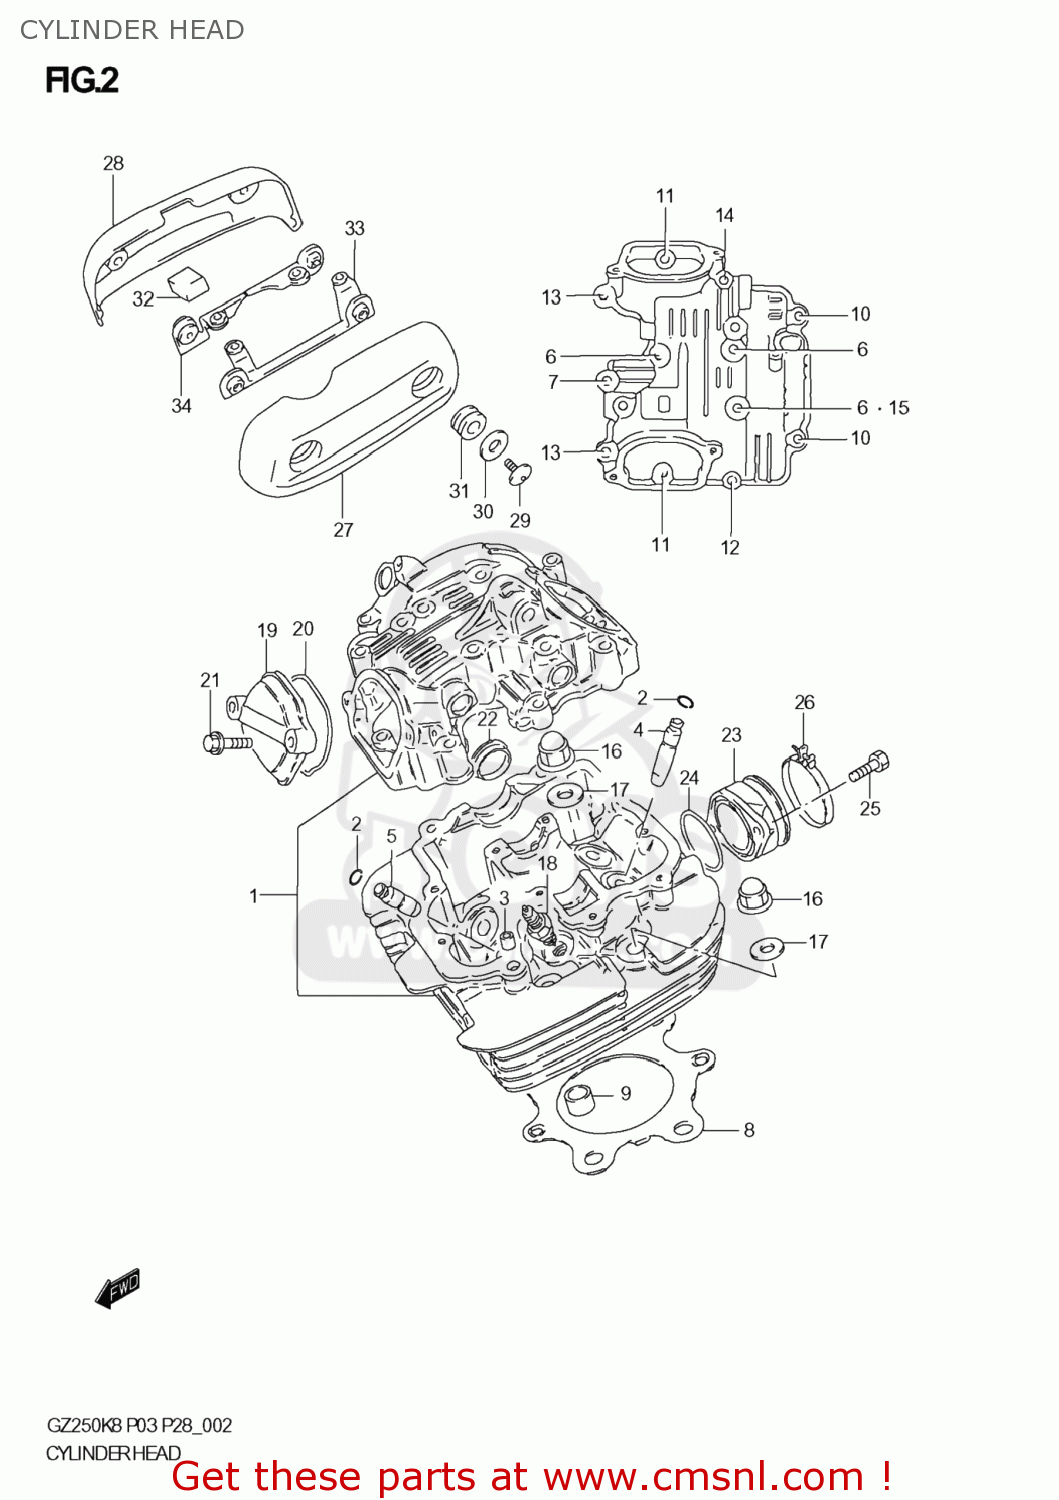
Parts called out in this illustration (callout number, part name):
1	HEAD ASSY,CYLINDER
2	RING,SNAP
3	PIN(6.2X8X11)
4	GUIDE,INTAKE VALVE
5	GUIDE,VALVE
6	BOLT
7	BOLT
8	GASKET,CYLINDER HEAD (NAS)
9	PIN
10	BOLT(6X120)
11	BOLT
12	BOLT
13	BOLT
14	BOLT
15	GASKET(5.8X13X1.2) (NAS)
16	NUT
17	GASKET(10.5X22X2) (NAS)
18	PLUG,SPARK(DR8EA)
19	CAP,INSPECTION
20	O RING(D:2.4,ID:23)
21	BOLT
22	PLUG(OD:30)
23	PIPE,INTAKE
24	O RING(D:2.4,ID:39.7)
25	SCREW
26	CLAMP
27	CAP,CYLINDER HEAD COVER,L
28	CAP,CYLINDER HEAD COVER,R
29	BOLT
30	WASHER(6.5X24X1.6)
31	CUSHION
32	DAMPER,HEAD CAP,R
33	BRACKET,HEAD CAP,L
34	BRACKET,HEAD CAP,R
